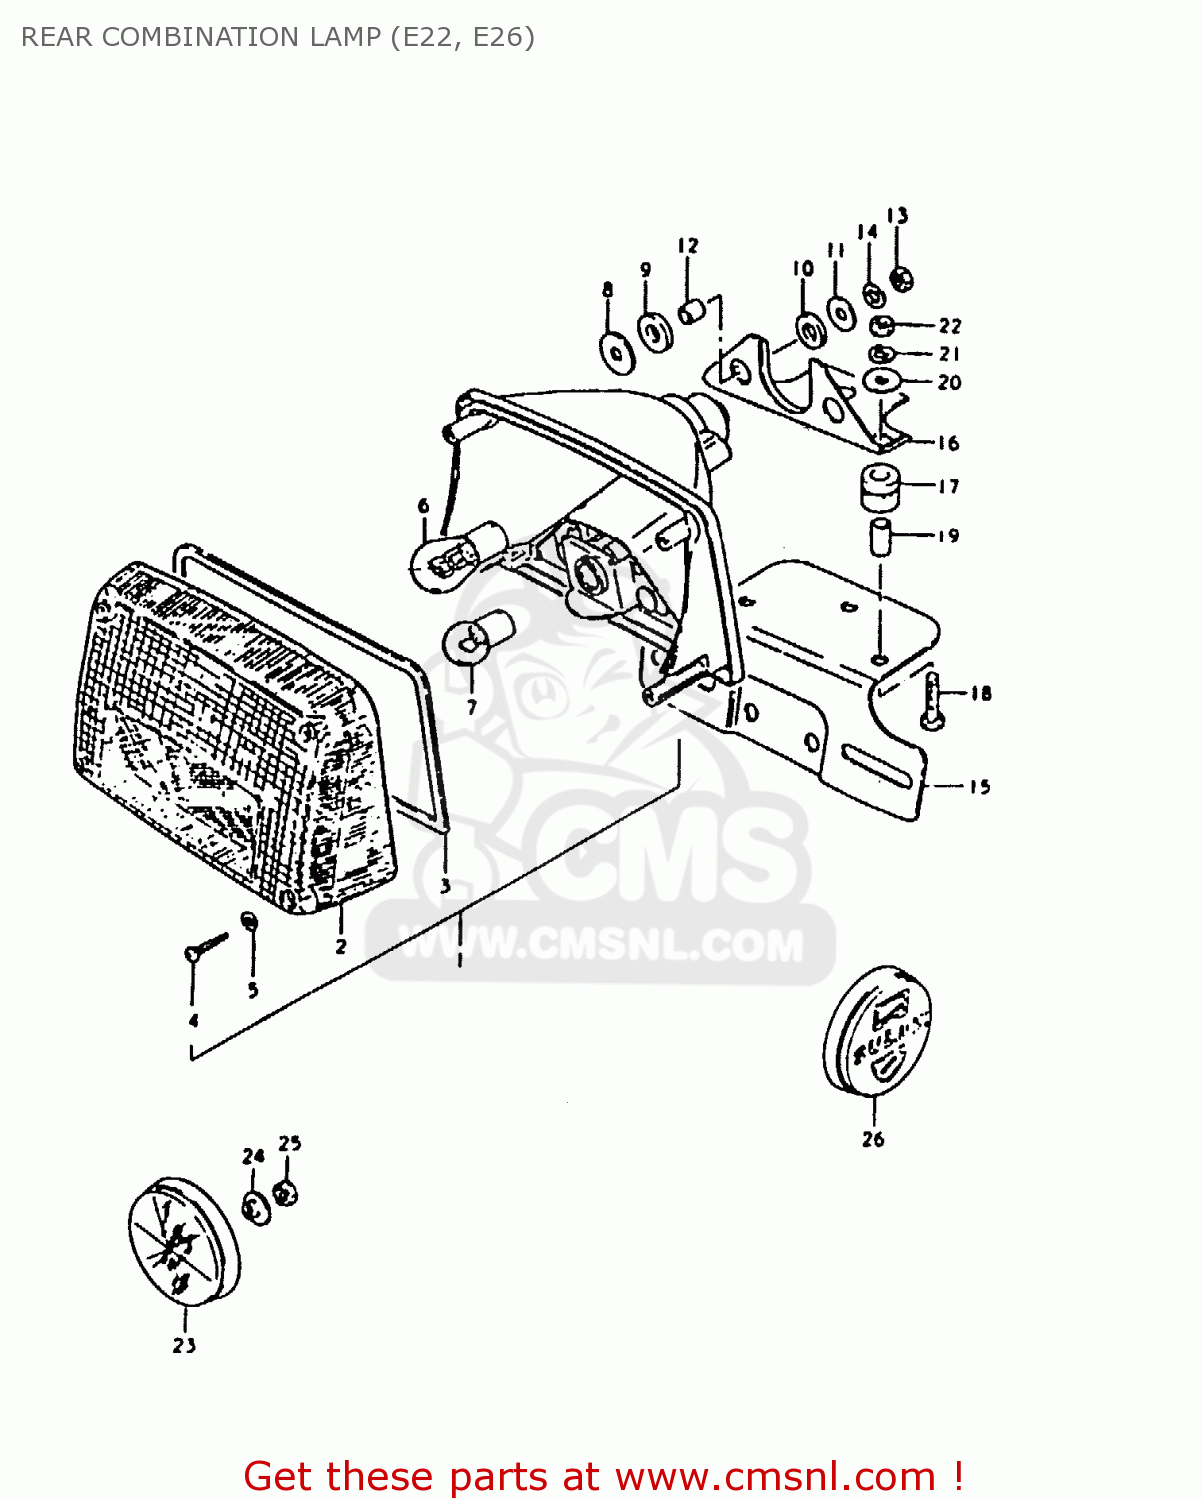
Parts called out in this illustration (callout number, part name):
1	LAMP, REAR COMBINATION
2	LENS
3	GASKET (NAS)
4	SCREW
5	GASKET (NAS)
6	BULB(12V21/5W)
7	BULB(12V10W,TOKAI DENSO)
8	WASHER
9	CUSHION
10	CUSHION
11	WASHER(6,5X22X1.6)
12	SPACER(6.1X9X7.5)
13	NUT
14	LOCK WASHER
15	BRACKET, LICENCE PLATE
16	BRACKET,LICENSE PLATE
17	CUSHION, BRACKET
18	BOLT
19	SPACER (6.4X9X15.5)
20	WASHER
21	LOCK WASHER
22	NUT
23	REFLECTOR,REFLEX
24	SPACER
25	NUT
26	EMBLEM, REAR SIDE
